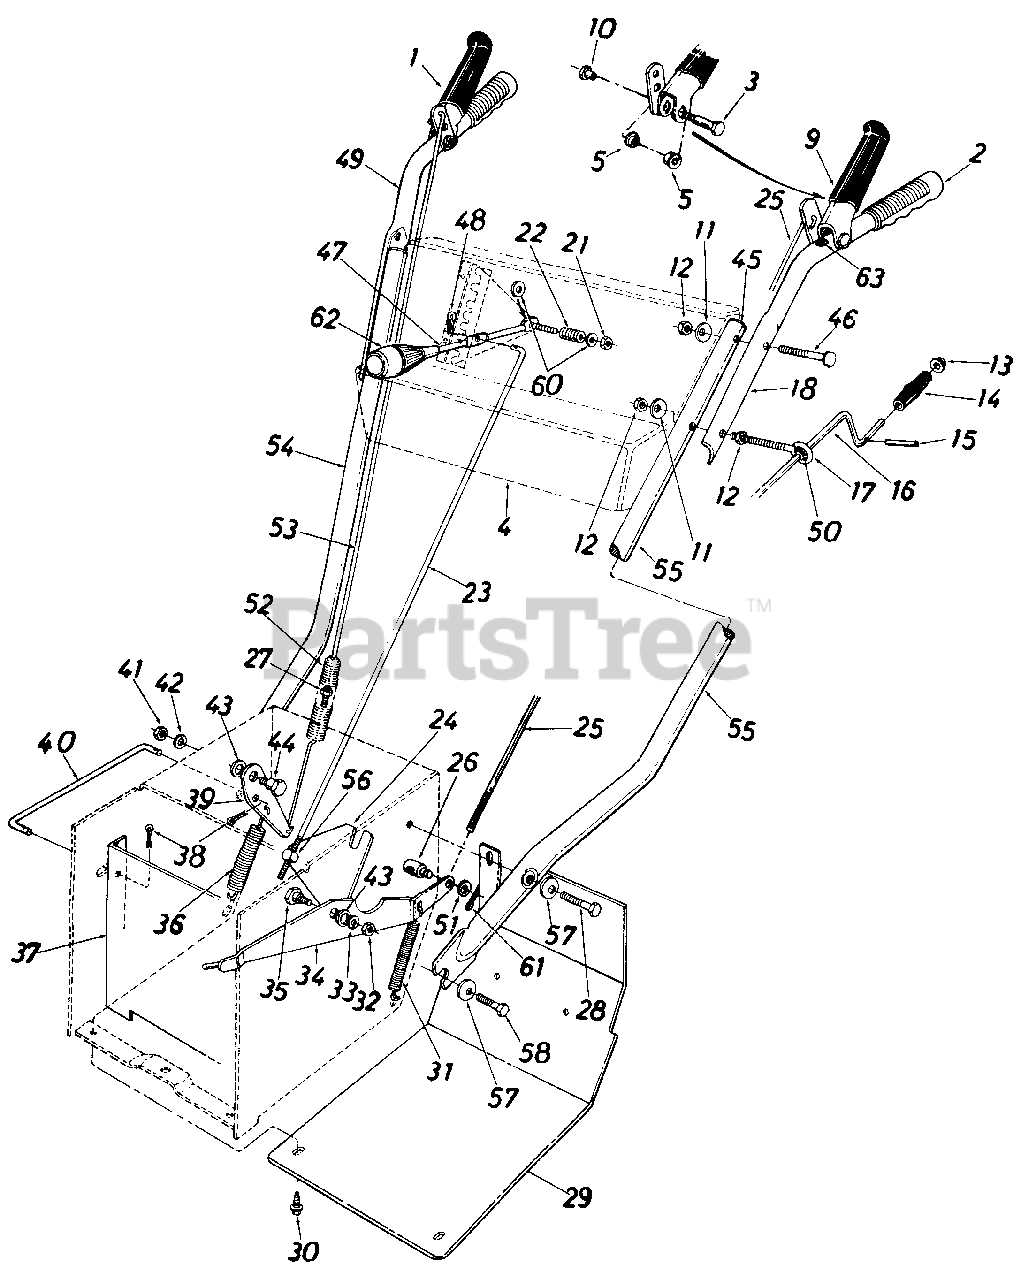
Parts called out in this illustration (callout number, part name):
1	Clutch Grip Ass'y.-R.H.
2	Grip
3	Shoulder Bolt .374 Dia. x 1.53" Lg.
4	Handle Panel Ass'y.
5	Hex Flange Plastic Bearing .380" I.D.
9	Clutch Grip Ass'y.-L.H.
10	Shoulder Nut 1/4-20 Thd.
11	Bell-Wash .34" I.D. x .88" O.D.
12	Hex Nut 5/16-18 Thd.
13	Push Nut 3/8" Rod
14	Knob 3/8" Rod
15	Roll Pin .12 Dia. x .63" Lg.
16	Chute Crank Ass'y. 39" Lg.
17	Eye Bolt 5/16-18 x 5.0" Lg.
18	Upper Handle-L.H. (Chrome)
21	Hex Ins. Jam L-Nut 5/16-18 Thd.
22	Compression Spring .50" O.D. x .88" Lg.
23	Shifting Rod 5/16" x 32.50" Lg.
24	Shifting Linkage Bracket
25	Lockout Rod .214" Dia. x 36.0" Lg.
26	Adjustment Ferrule 1/4-20
27	Hex Ins. L-Nut 1/4-20 Thd.
28	Hex Bolt 3/8-16 x 2.00" Lg.
29	Frame Cover
30	Hex Wash. Self-Tap Scr. 1/4-20 x .50" Lg.
31	Extension Spring .38" O.D. x 3.25" Lg.
32	Hex Jam Nut 3/8-16 Thd.
33	L-Wash. 3/8" I.D.*
34	Auger Clutch Bracket Ass'y.
35	Shld. Bolt .625" Dia. x .170
36	Extension Spring .75" O.D. x 4.31" Lg.
37	Drive Pulley Support Brkt. Ass'y.
38	Cotter Pin 3/32" Dia. x .75" Lg.*
39	Drive Clutch Bracket
40	Drive Clutch Rod
41	Hex Jam Nut 3/8-16 Thd.*
42	L-Wash. 3/8" I.D.
43	Bell-Wash. .40" I.D. x 1.13 O.D.
44	Shld. Bolt.625" Dia. x .170
45	Plastic Plug
46	Carriage Bolt 5/16-18 x 2.0"-Lg.
47	Shift Handle
48	Int. Cotter Pin 5/16" Dia.
49	Upper Handle-R.H. (Chrome)
50	Plastic Bushing
51	Fl-Wash. .28" I.D. x .62" O.D.
52	Extension Spring .75" O.D. x 5.00" Lg.
53	Lockout Rod .214" Dia. x 32" Lg.
54	Lower Handle-R.H. (Chrome)
55	Lower Handle-L.H. (Chrome)
56	Adjustment Ferrule
57	Bell-Wash. .40" I.D. x .88" O.D.
58	Hex Wash. Self-Tap Scr. 3/8-16 x 75n Lg.
60	Fl-Wash. .344" I.D. x .62" O.D.
61	Cotter Pin 3/32" Dia.
63	Push Cap
